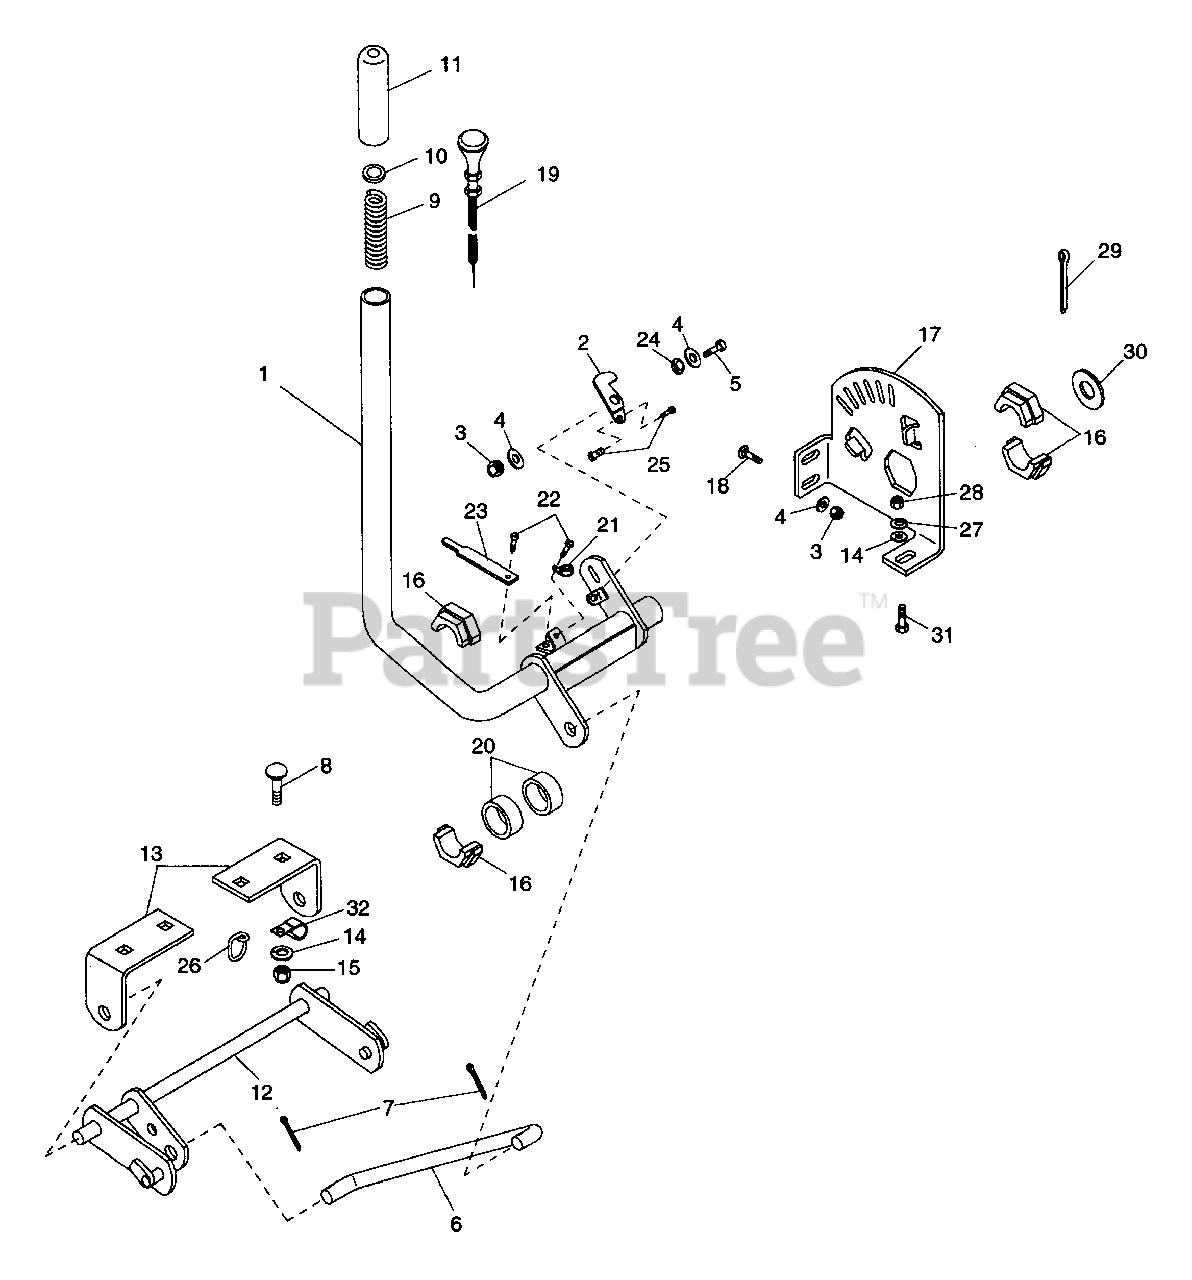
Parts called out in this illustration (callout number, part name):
1	LIFT LEVER
3	NUT-LK .312-18 GR A PL
4	WSHR-FL-STL.312X.734X.065PL
5	BLT-HEX .31-18X.75 PL GR5
6	LIFT LINK
7	PIN-COTR .12X1.0 PL
8	BLT-RDHDSQSHNK .38-16X1.00 PL
9	SG-COMP .048X.59X2.06 WLD9
10	WSHR-FL-STL.312X.734X.065PL
11	HANDLE GRIP
12	CENTER LIFT LEVER
13	CENTER LIFT BRACKET
14	WSHR-LK .375X.094 MED PL
15	NUT-HEX .375-16
16	BSHG-FLG 1.014X1.750X.72
17	QUADRANT
18	BLT-RDHDSQNK .312-18X.62 PL
19	PUSH-PULL CONTROL
20	SPACER 1.070X1.380X.615
21	CABLE CLAMP NON SKID
22	SCR-TAP 10-16X.50 HWH PL AB
23	INDICATOR
24	SPACER BUSHING .5 X .32 X .21
25	SWIVEL ASSY
26	BELT FINGER
27	WSHR-FL-STL.406X.812X.065PL
28	NUT-LK-CTR .375-16 GR A PL
29	PIN-COTR .25X1.50 ST PL
30	WSHR-FL-STL 1.016X1.625X.045
31	BLT-HEX .38-16X1.00 PL
32	J-CLAMP
